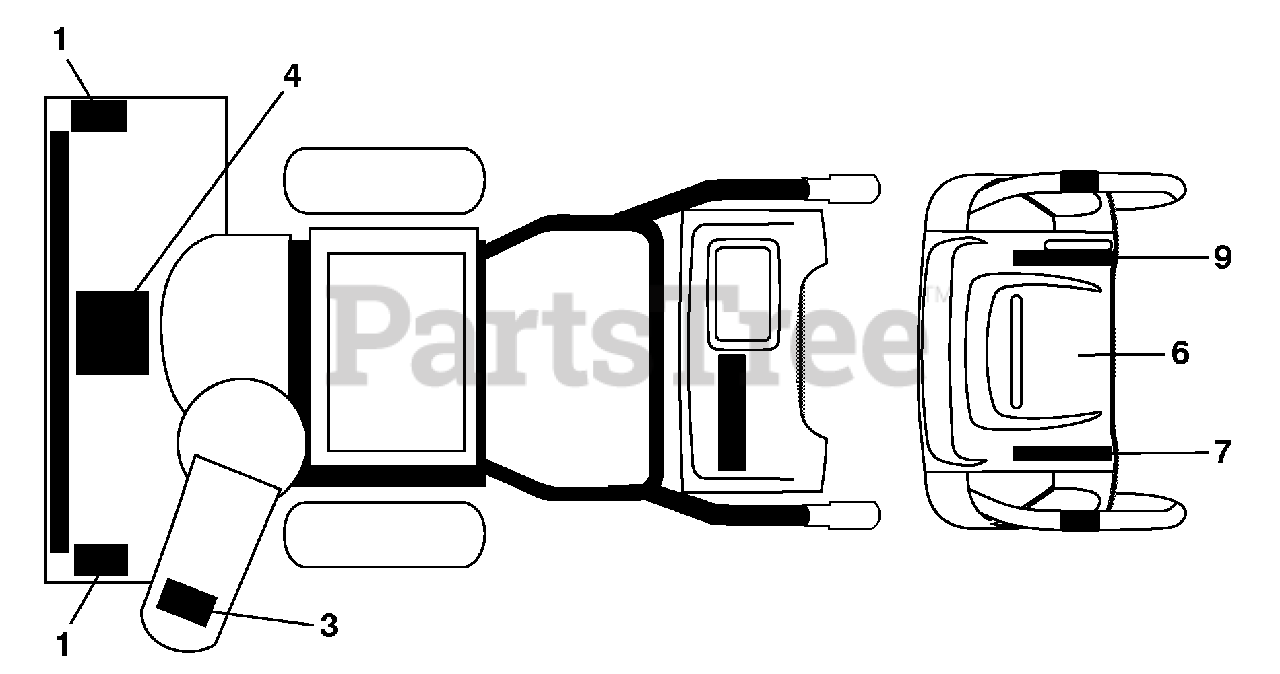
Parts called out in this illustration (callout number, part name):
1	DECAL, DANGER
3	DECAL, DANGER, DEFLECTOR
4	DECAL, DANGER
6	DECAL, INSTRUCTION
7	DECAL, TRACTION LEVER
9	DECAL, SPEED CONTROL
9	OWNER'S MANUAL, ENGLISH / SPANISH
